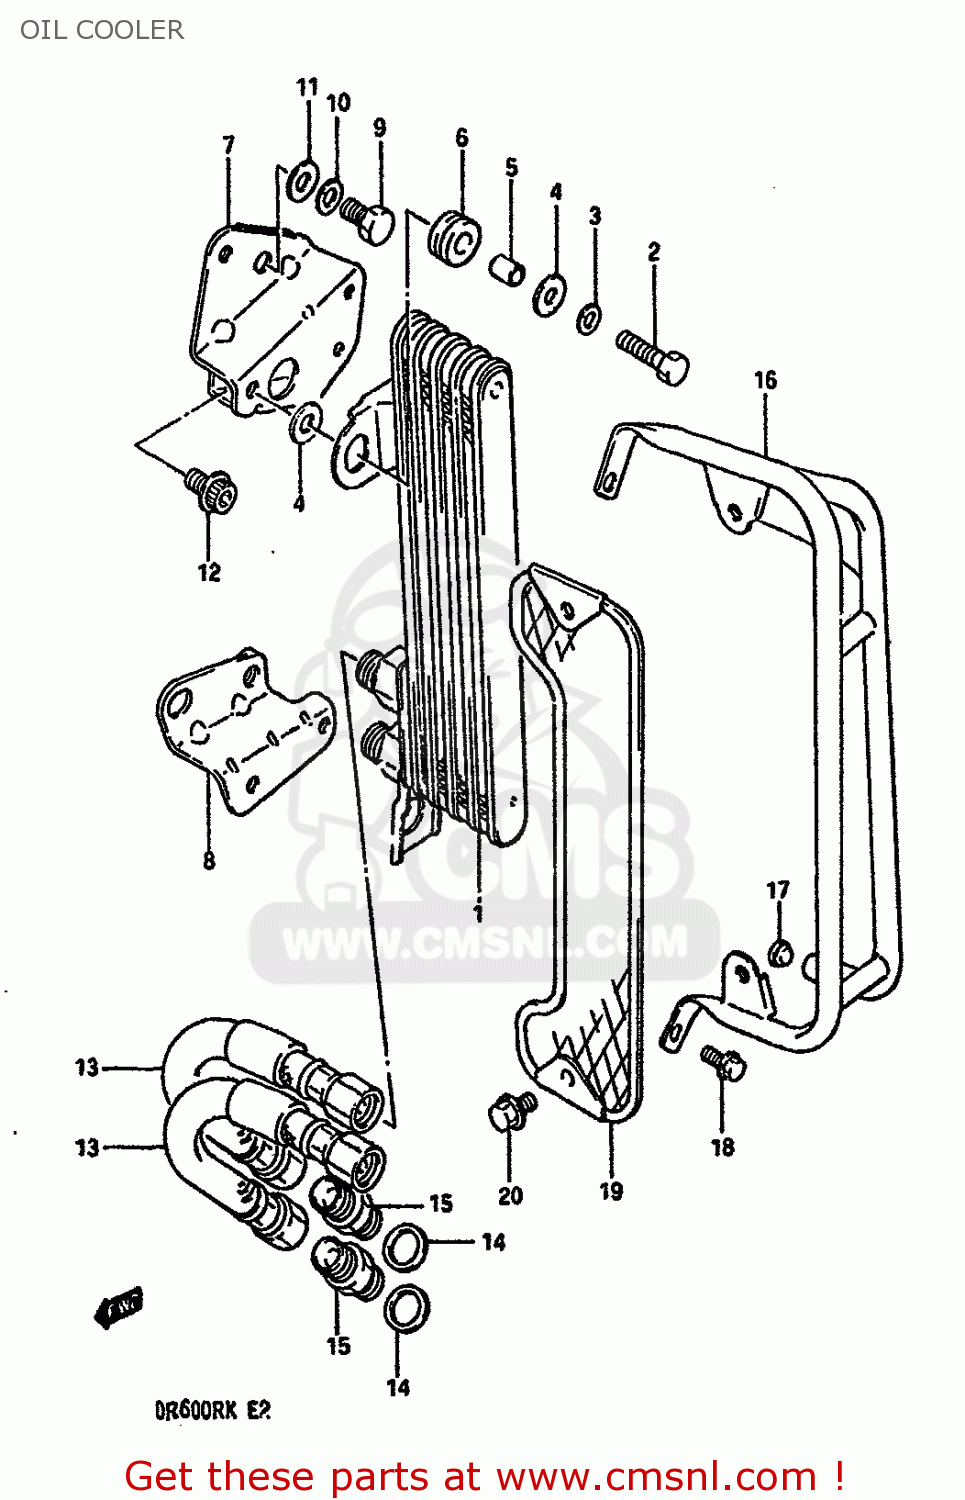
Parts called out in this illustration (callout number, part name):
1	COOLER ASSEMBLY,ENGINE OIL
2	BOLT
3	WASHER,LOCK
4	WASHER (6.5X18X1.6)
5	SPACER (6.8X10X10)
6	CUSHION
7	BRACKET,OIL COOLER NO.1
8	BRACKET,OIL COOLER NO.2
9	BOLT
10	WASHER,LOCK,8.
11	WASHER
12	BOLT
13	HOSE,OIL COOLER
14	GASKET(14X20X1.5) (NAS)
15	BOLT UNION
16	GUARD,OIL COOLER
17	CAP(OD:10)
18	BOLT
19	BUMPER,OIL COOLER
20	BOLT 6X12
